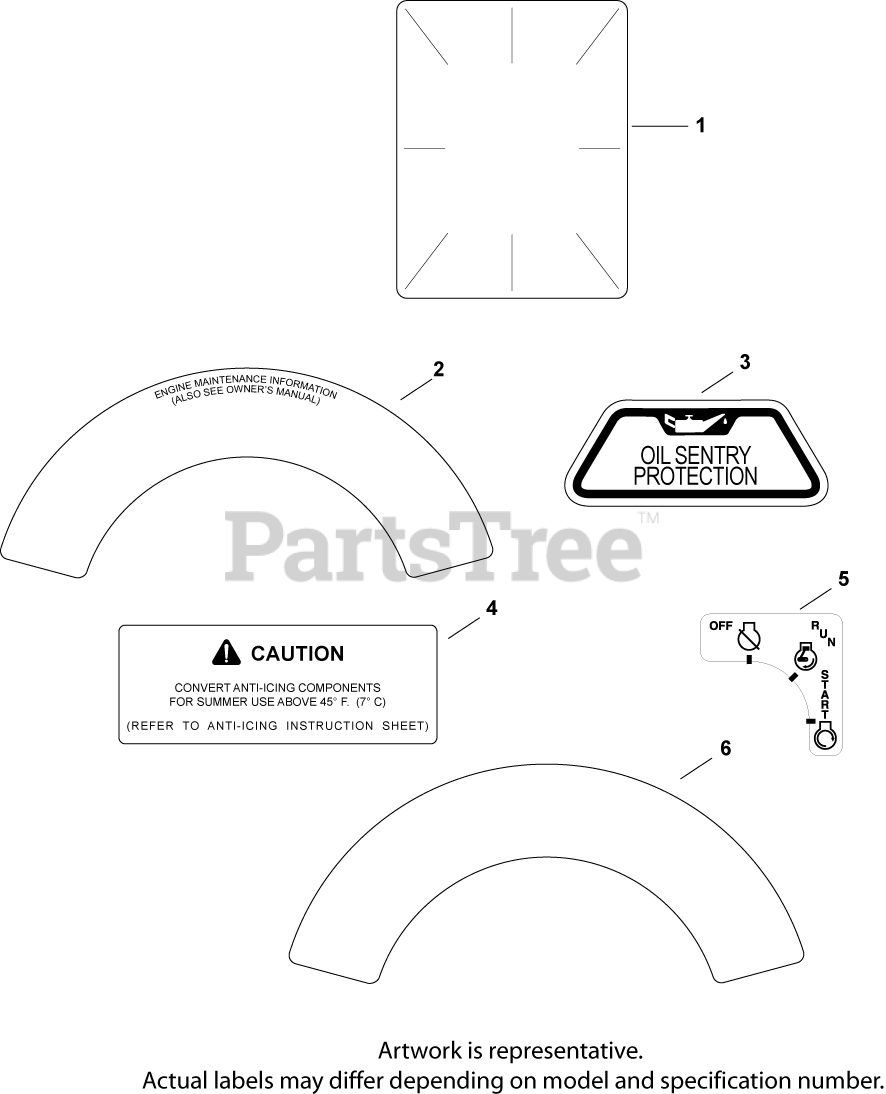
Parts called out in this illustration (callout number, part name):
1	DECAL, CLEAR LAMINATE USE 25 113 70-S
2	DECAL, ENGINE MAINTENANCE-DISC.
3	DECAL, OIL SENTRY - (#DSC)
4	DECAL, ANTI-ICING
5	DECAL, KEY SWITCH
6	DECAL, 20 HP - DISCONTINUED
